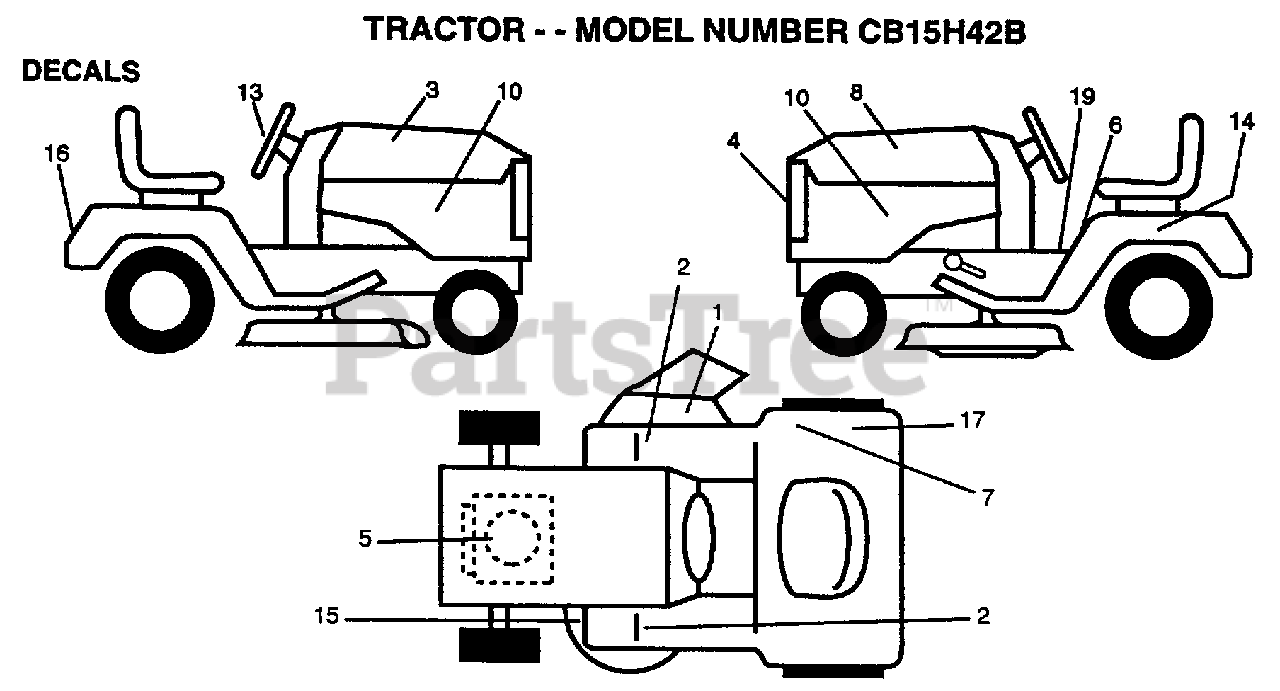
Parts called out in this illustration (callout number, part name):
1	DECAL.DANGER.CUTF
2	"PAD,FOOTREST"
3	DECAL.HOOD.RH.
4	DECAL.GRILLE.COOP
6	DECAL.READ.O.MANU
7	DECAL.EURO.ST.CE.
8	DECAL.HOOD.LH
10	DECAL.PNL.15H107
13	DECAL.INS.WHL.STG
14	DECAL.BATRY.3-3908
15	DECAL
16	DECAL.FEND.COOPER
19	DECAL BRAK PARK
